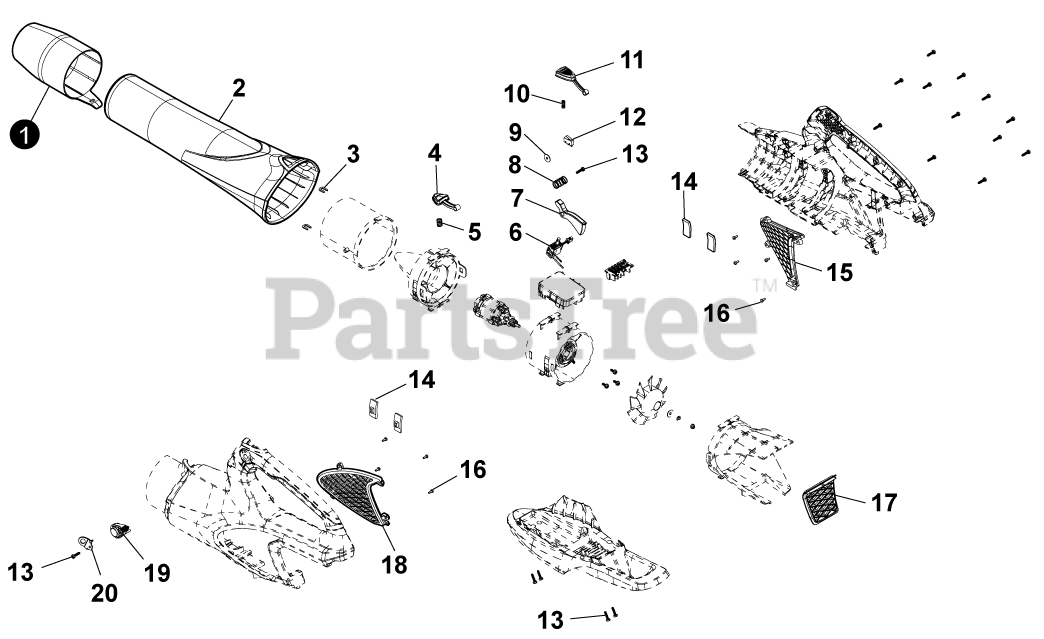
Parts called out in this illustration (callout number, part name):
1	BLOWER TIP
2	BLOW PIPE
3	RETAINER
4	BUTTON, RELEASE
5	SPRING, COMPRESSION
6	SWITCH, SPEED-CONTROL
8	SPRING, COMPRESSION
11	BUTTON, TURBO
12	SWITCH, MICRO
14	INSULATOR, MOTOR
15	VENT, RIGHT
17	VENT, REAR
18	VENT, LEFT
19	KNOB, CRUISE CONTROL
20	HOOK, STRAP
